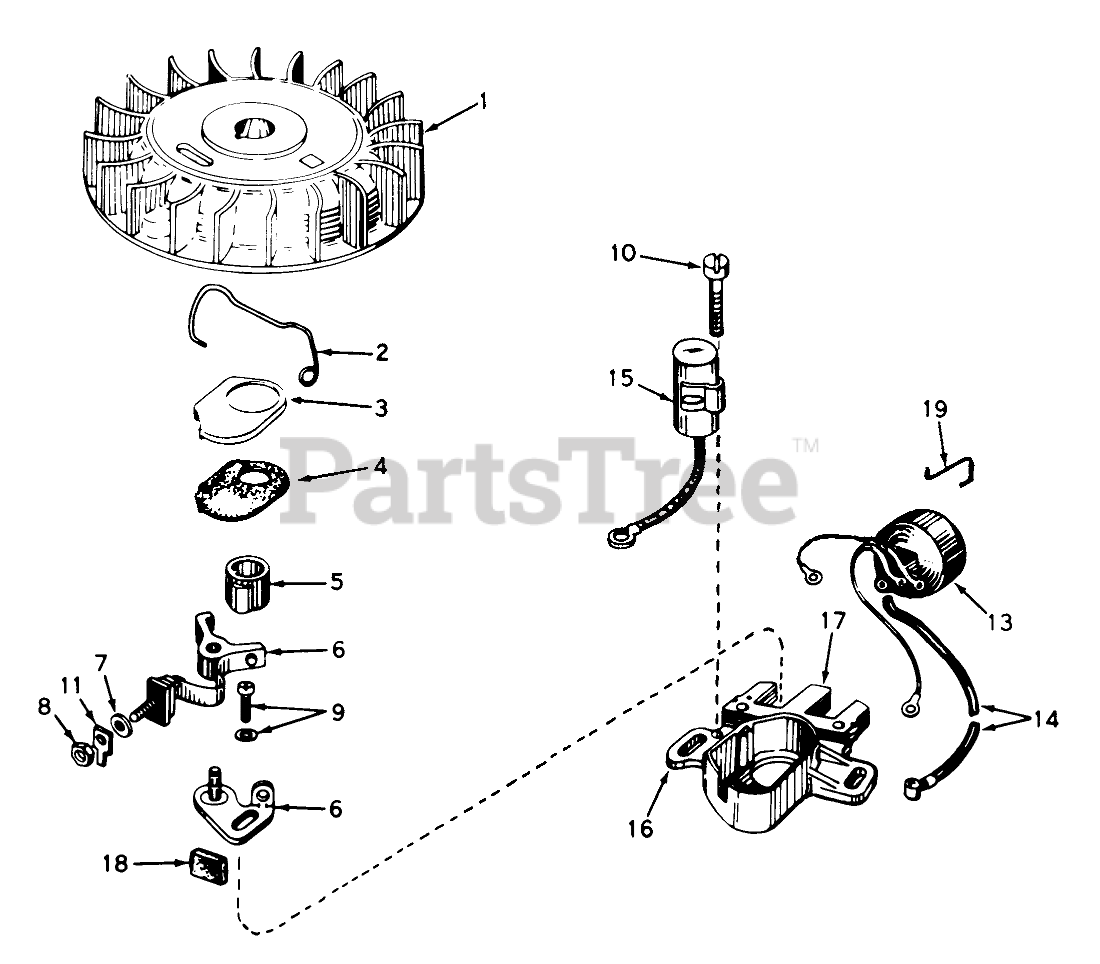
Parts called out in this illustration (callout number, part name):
1	A Flywheel (Incl. Nos. 3 & 4)
2	Spring Breaker Box
3	Cover-Dust
4	Gasket, Dust Cover
5	Cam, Breaker
6	Breaker Assy.
9	Breaker Screw
10	Condenser Screw
11	Terminal, Ground
13	Coil Assembly (Incl. No. 14)
14	Wire, Lead
15	Condenser
16	Core & Plate
17	Stator Assembly (Incl. Nos. 2, 3, 4, 6 thru 11, 13, 15, 16, 18 & 19)
18	Felt,Cam Wiper
19	Clip, Coil
